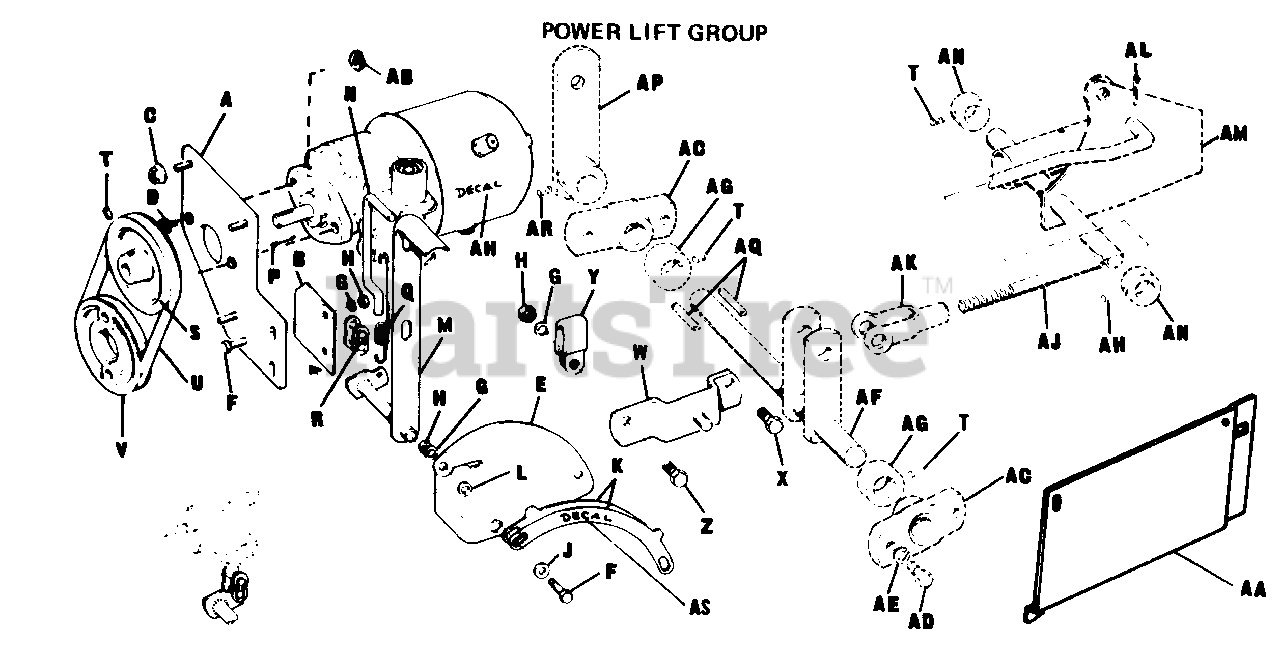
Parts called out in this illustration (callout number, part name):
A	Pump Support Assembly
B	Angle Bracket
C	Hex. Nut, Whiz Lock, 5/16"-18
D	Machine Screw, Flat Hd. 3/8-16 x 1-1/4" lg.
F	Hex. Cap Screw, 1/4"-20 x 3/4"
G	Lock Washer, 1/4"
H	Full Hex. Nut, 1/4"-20
J	Plain Washer, 1/4"
K	Stop Plate
M	Lever Assembly
N	Latch Rod
P	Cotter Pin, 3/32" x 5/8"
R	Connecting Link
S	Pump Pulley
T	Set Screw, 5/16"-18 x 5/16"
V	Drive Pulley
W	Pivot Bar Assembly
X	Hex. Cap Screw, 5/16"-18 x 1"
Y	Hose Clamp
Z	Hex Cap Screw, 1/4"-20 x 1"
AA	Panel, Side L.H.
AB	Nut Whiz-lock Flange 3/8"-16
AC	Lift Lever Bearing
AD	Hex. Cap Screw, 3/8"-16 x 7/8"
AE	Lock Washer, 3/8"
AF	Lift Shaft Assembly
AG	Set Collar
AK	Adj. Yoke End
AL	Cotter Pin, 1/8" Dia. x 1"
AM	Tiller Lift Assembly
AN	Set Collar
AP	Front Lift Lever Assembly
AR	Set Screw, 5/16"-18 x 1/4"
